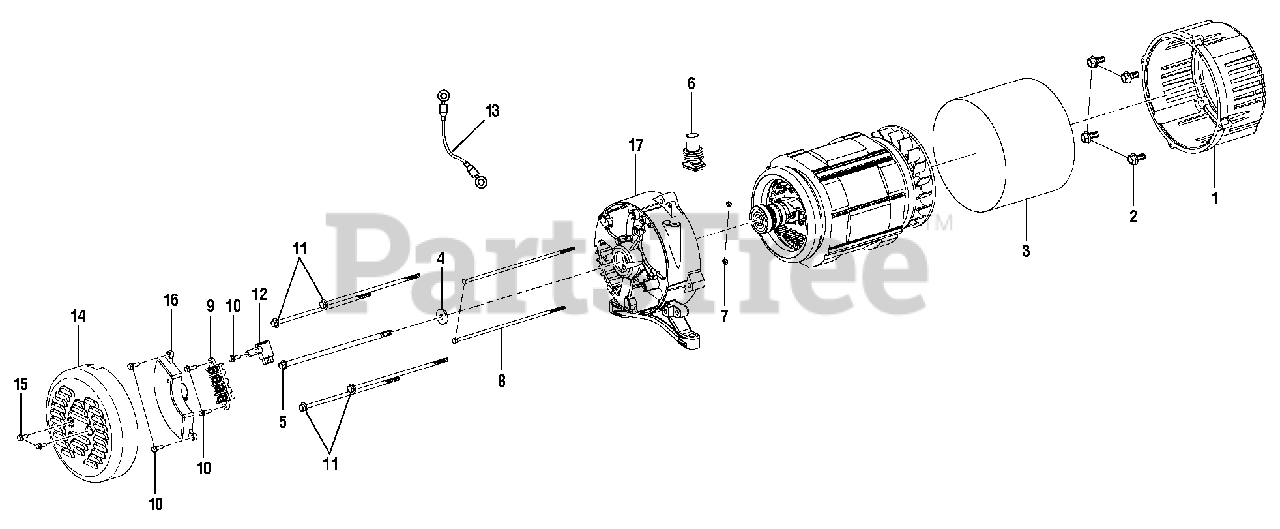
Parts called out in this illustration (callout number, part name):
1	Adaptor Housing
2	Bolt (3/8-16 x 1- 1/4 in.)
3	Generator Head Cover
4	Washer (Rotor)
5	Rotor Bolt
6	Rubber Boot
7	Hex Nut (M5)
8	Bolt (M5)
9	Terminal Block
10	Bolt (M5 x 16 mm)
11	Bolt (Stator)
12	Brush Assembly
13	Bonding Wire
14	Brush Cover
15	Bolt (M5 x 12 mm)
16	Automatic Voltage Regulator
17	Bearing Housing
